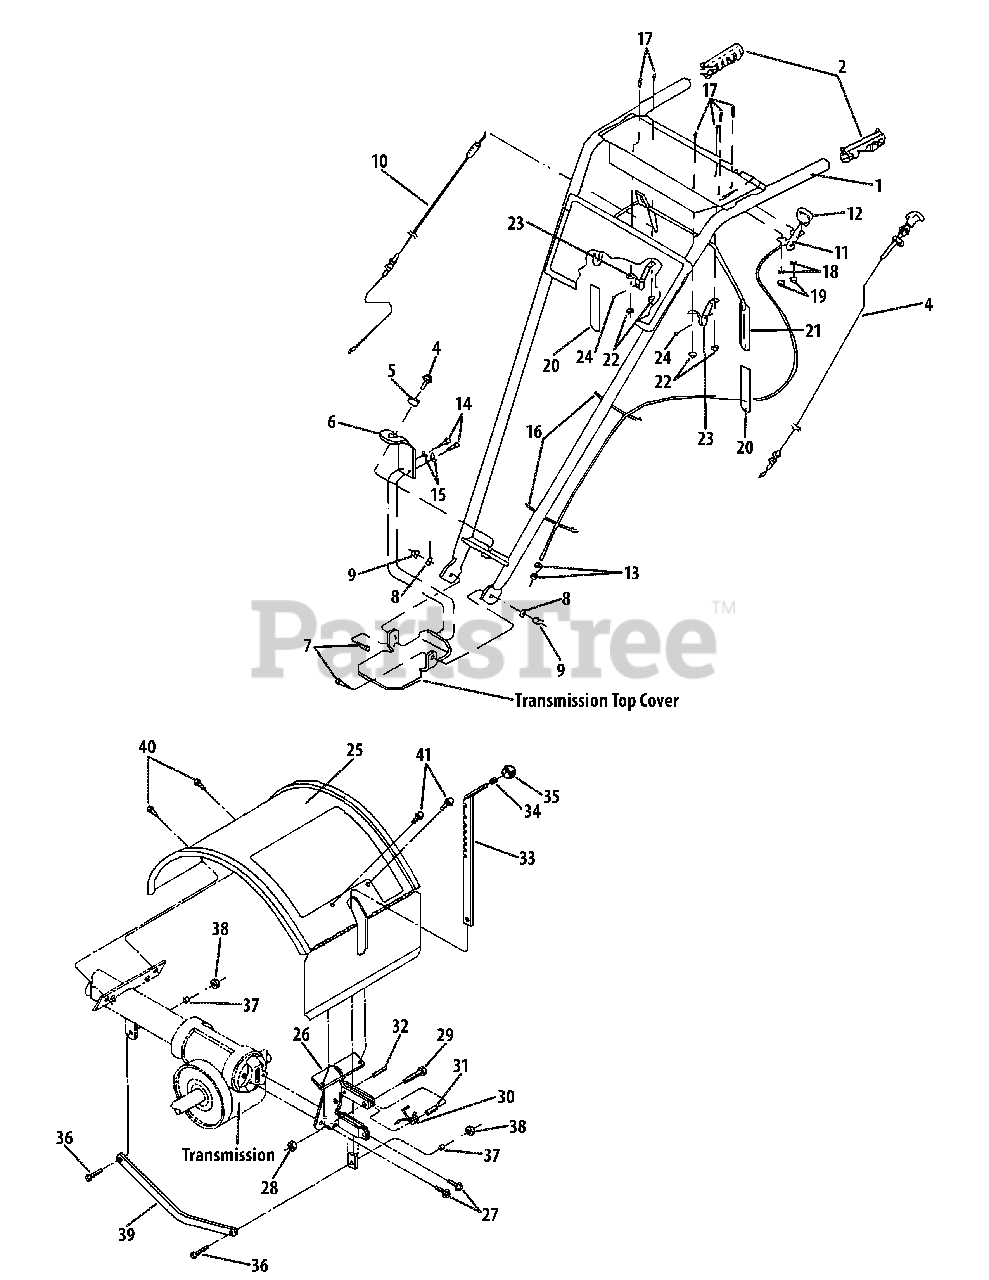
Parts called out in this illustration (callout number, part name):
1	Handlebars
3	Reverse Clutch Control Cable
4	Height Adjustment Screw
5	Keyed Washer
6	Handlebar Hgt. Adjustment Bracket
7	Hex Hd. Screw, 3/8 -16 x 1
8	Plain Washer, 3/8
9	Hex Locknut, 3/8 -16
10	Forward Clutch Control Cable
11	Wheel Gear Control & Cable Ass.
12	Wheel Gear Control Lever Knob
13	Hex Nut, 5/16-24
14	Hex Head Screw, 3/8-16 x 5/8
15	Lockwasher,3/8
16	Cable Ties
17	Round Head Screw, #10-32 x 1/2
18	Lockwasher, #10
19	Hex Nut, #10-32
21	Forward Clutch Bail
23	Bail Support Bracket
24	Self-tapping Screw, 1/4-20 x 1/2
27	Hex Flange Screw, 5/16-18 x 5/8
28	Hex Locknut, 1/4-20
29	Hex Head Screw, 1/4-20 x 1
32	Roll Pin (spiral),1/4 x 1
33	Depth Regulator
34	Retaining Ring
35	Depth Regulator Knob
36	Hex Head Screw, 3/8-16 x 1-1/4
37	Drag Bar Bushing
38	Hex Nut, 3/8 -16
39	Drag Bar
40	Self-tapping Screw, 5/16-18 x 5/8
41	Self-tapping Screw , 1/4-20 x 1/2
